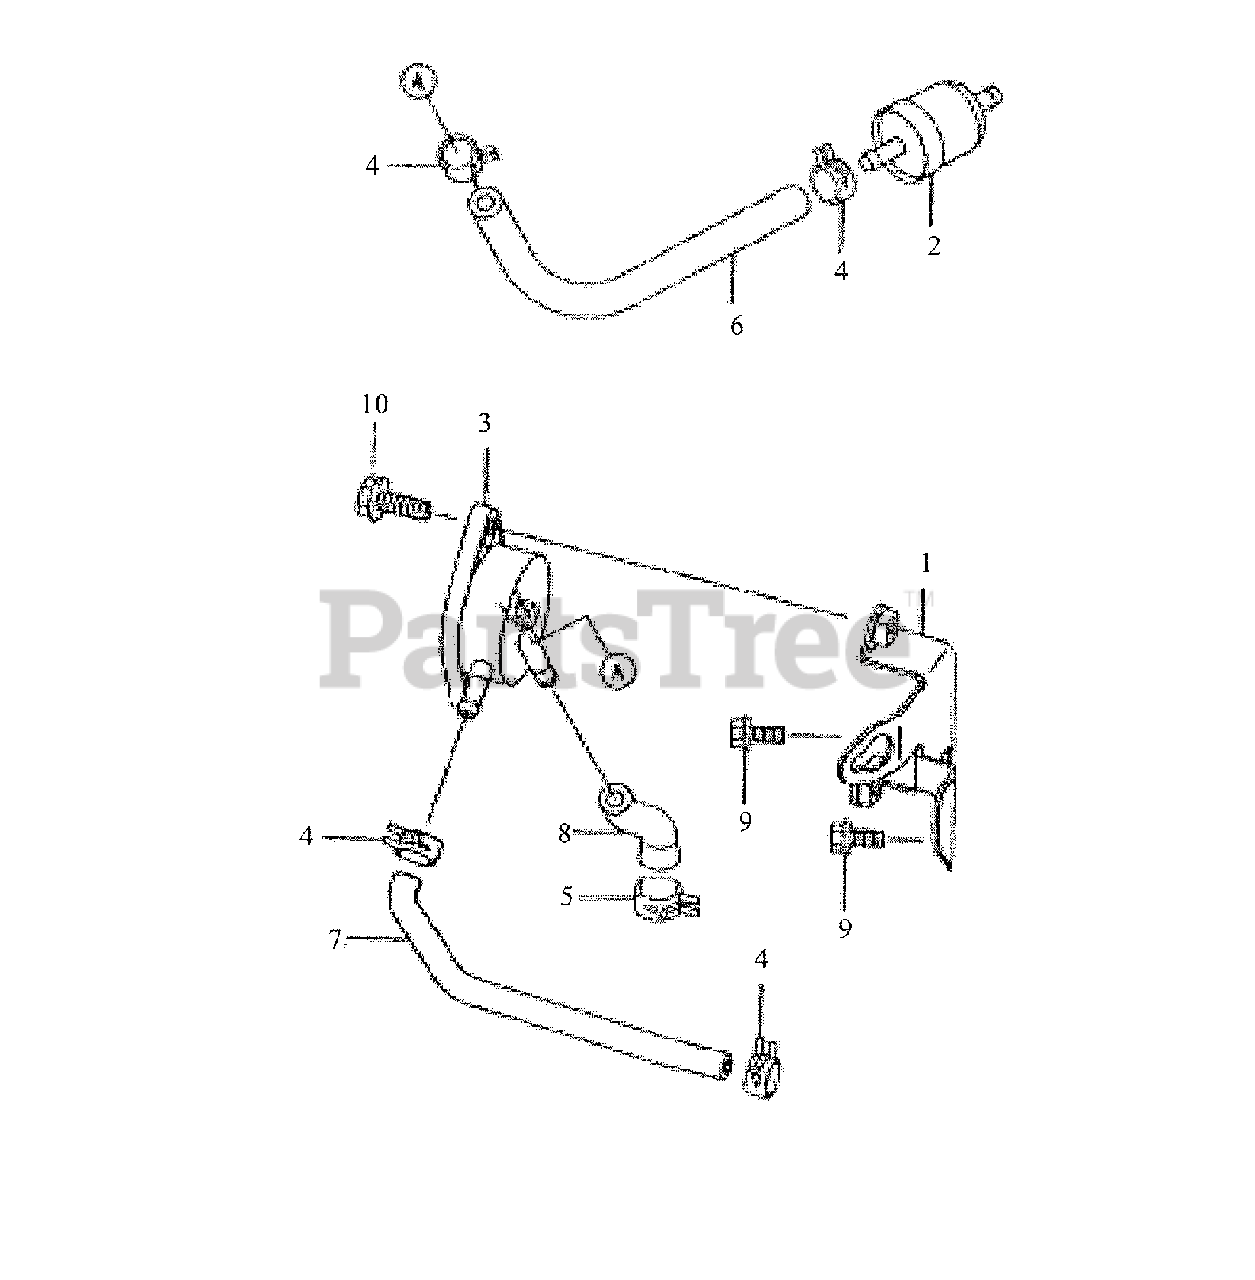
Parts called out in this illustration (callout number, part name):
1	Bracket
2	Filter-Fuel
3	Pump-Fuel
4	Clamp
6	Tube 6.35x12.7x160
7	Tube
8	Tube
9	Bolt-Flange
10	Bolt-Flange
